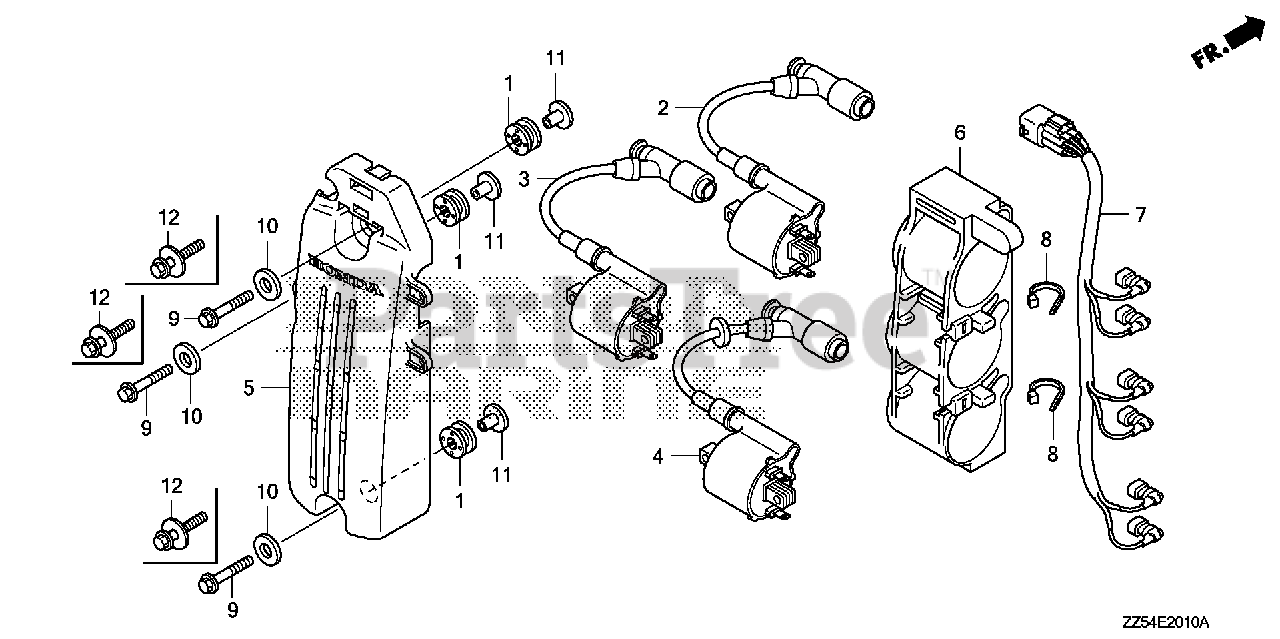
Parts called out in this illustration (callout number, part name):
1	GROMMET, ELECTRONIC PARTS CASE
2	COIL, IGNITION (1)
3	COIL, IGNITION (2)
4	COIL, IGNITION (3)
5	CASE, IGNITION COIL
6	SUSPENSION, IGNITION COIL
7	WIRE ASSY., IGNITION COIL
8	BAND, WIRE
9	BOLT, FLANGE (6X28)
10	WASHER, PLAIN (6MM)
11	COLLAR, MOUNTING (6MM)
12	BOLT-WASHER (6X25)
